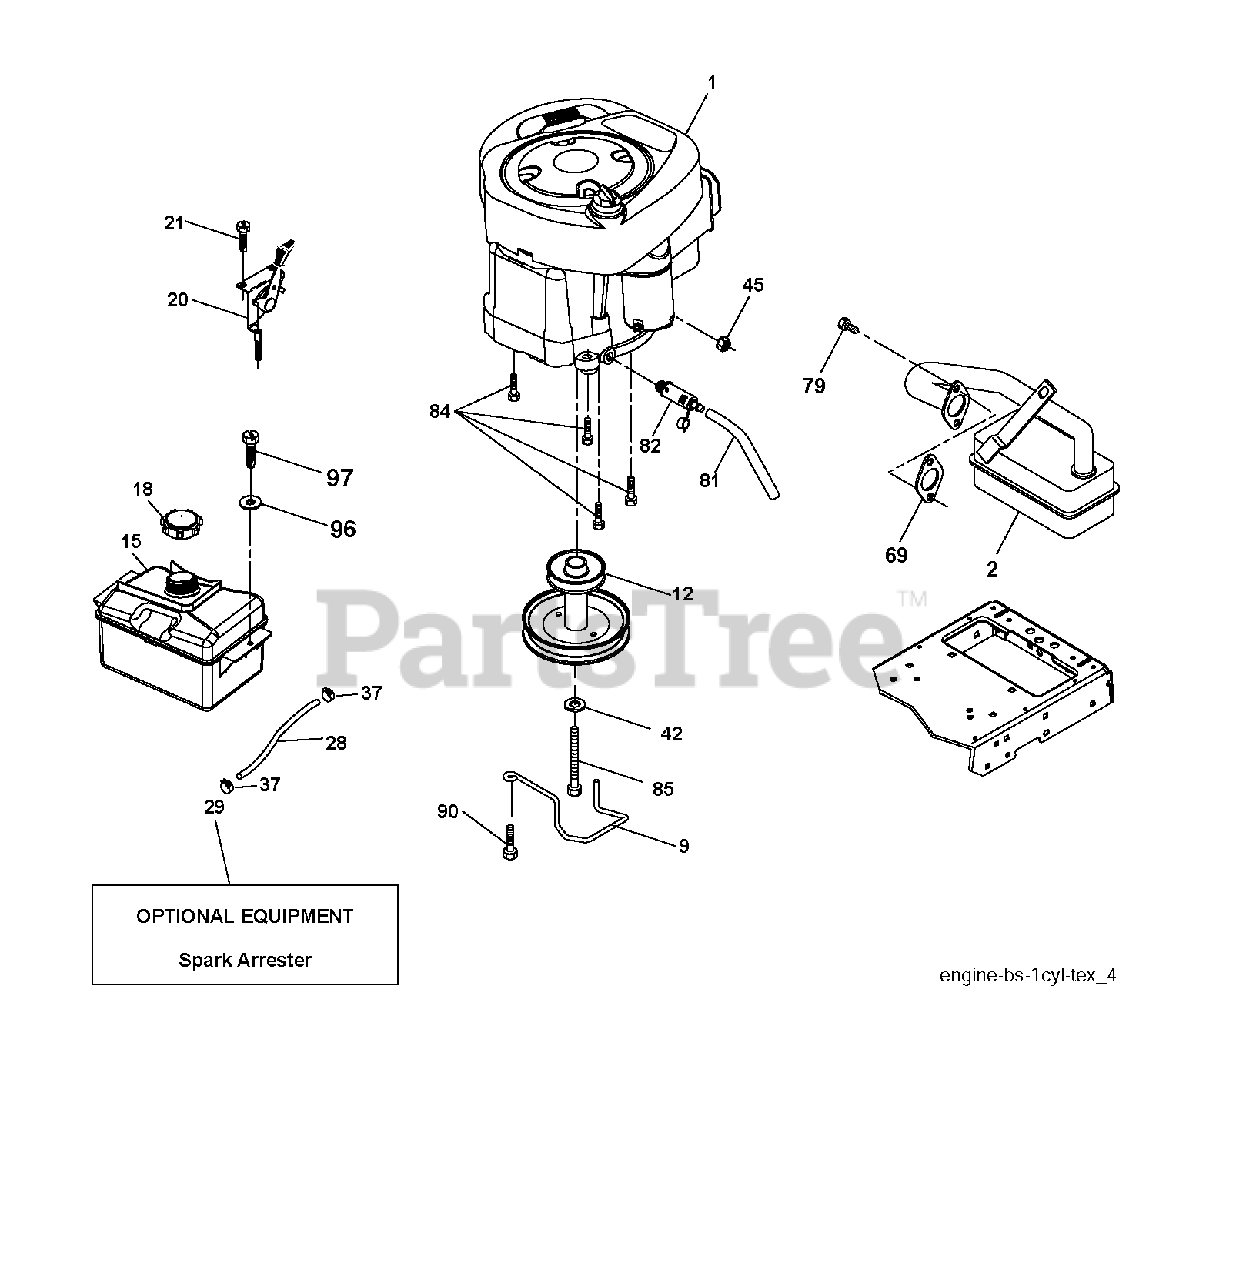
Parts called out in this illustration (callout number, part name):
9	KEEPER.BELT.ENGINE.3.25
12	PULLEY ENGINE
15	TANK FUEL FRT 1.5 GAL
18	FUEL CAP
20	CONTROL.TH/CK.C.
21	SCREW.#10 X 0.750.BOS THREAD
28	LINE.FUEL.20
29	ARRESTER SPARK (OPTIONAL)
37	HOSE CLAMP
42	LOCKWASHER
45	NUT
69	REPL BY 532 27 22-93
79	SCREW.SOCKET HD.5/16-1
81	TUBE, DRAIN OIL ASM.
82	PLUG DRAIN OIL EASY
84	SCREW.3/8-16
85	BOLT HEX 7/16-20X4-1/4"
90	SCREW 3/8-16X1
97	SCREW HEXWSHR 1/4-20X3/4
